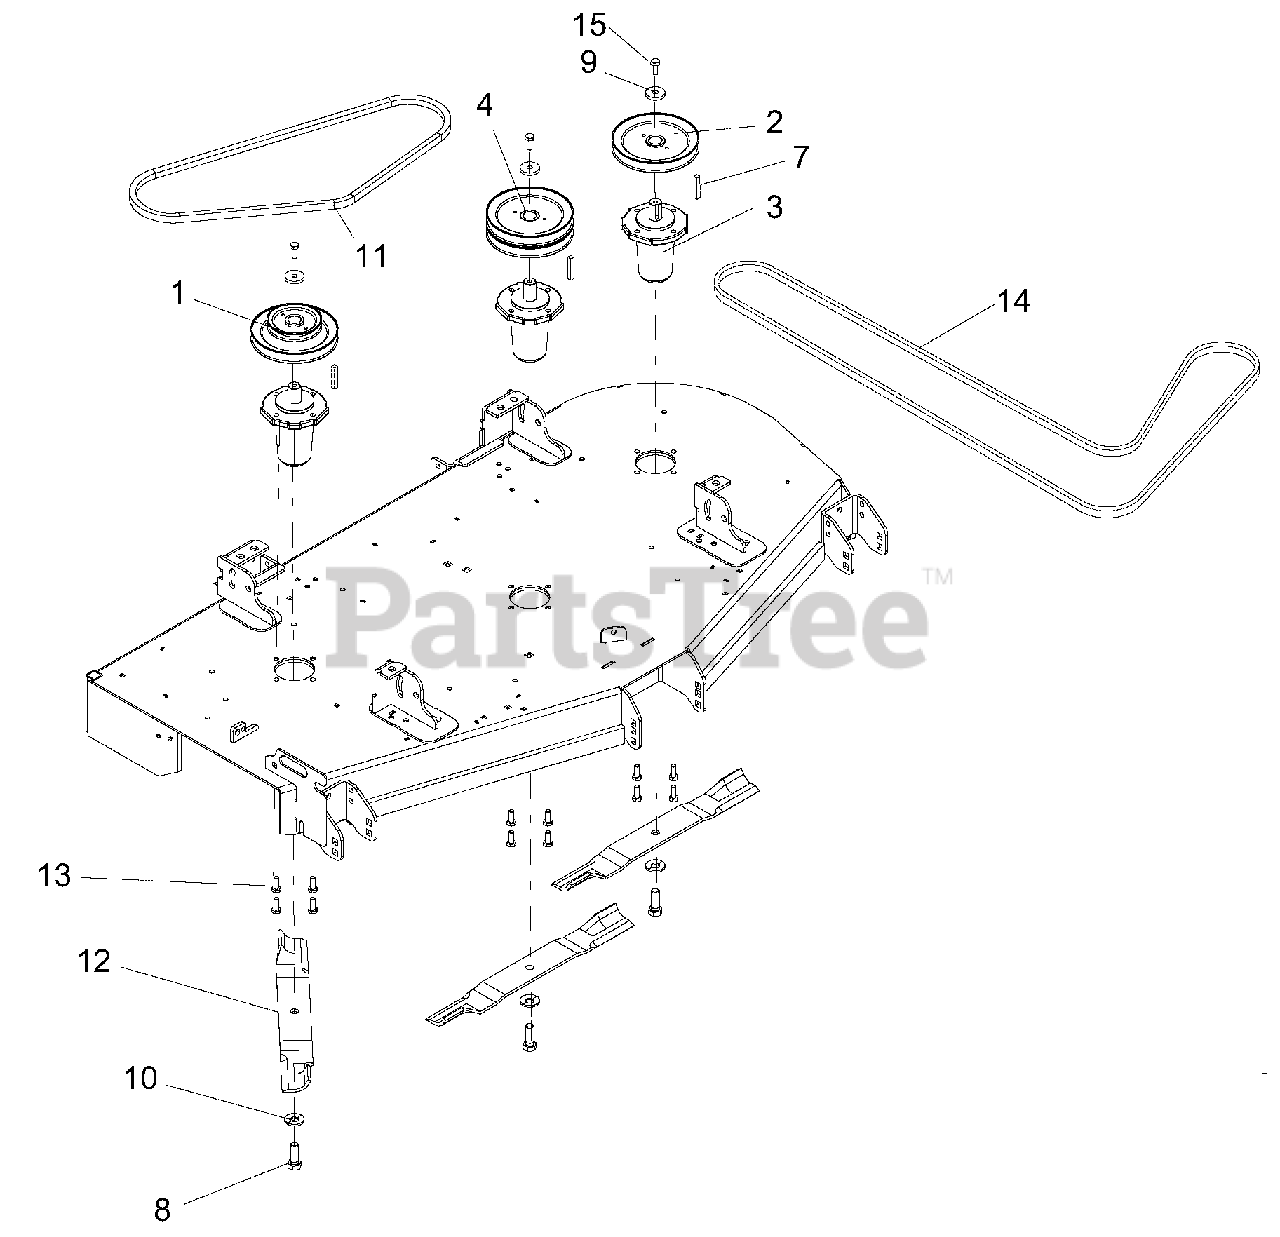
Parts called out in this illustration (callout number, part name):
1	PULLEY, DOUBLE-1" ID X 6.75" OD (992236)
2	PULLEY, V-1" ID X 6.75" OD (992236)
3	ASSEMBLY, MAINTENANCE FREE SPINDLE
4	PULLEY, DOUBLE 1"ID X 6.75"OD (992236)
7	KEY, SQ .25X.25X1.00 RC 40-50
8	BLT, HEX .62-18X1.75 GR8 YWZC
9	RETAINER, SHEAVE
10	WSHR, BLVL .63X1.625X.14
11	BELT, B 63.00 RAW COGGED (992236)
12	BLADE, MOWER 60" (992236)
13	BOLT, HEX .38-16 X 1.0 GRADE 8
14	HEX BELT, BB-WRAPPED CLUTCHING (992236)
15	BLT-HEX .38-16X2.75 GR8 YWZC
